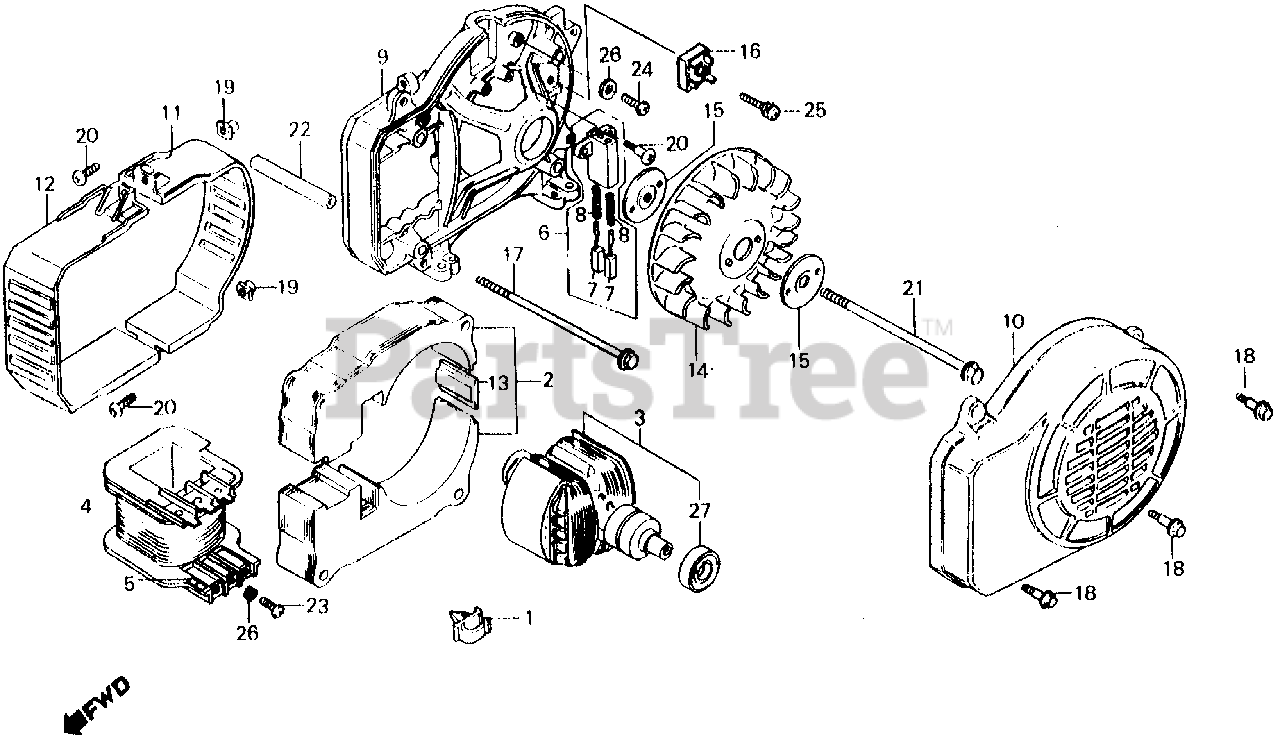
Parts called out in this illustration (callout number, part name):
1	CLAMP, D.C. CABLE
2	CORE SET, STATOR
3	ROTOR (NOT AVAILABLE)
4	BOBBIN, STATOR COIL (NOT AVAILABLE)
5	MARK, WIRE COLOR
6	HOLDER ASSY., BRUSH
8	SPRING, BRUSH
9	HOUSING, RR. (NOT AVAILABLE)
10	COVER, GENERATOR END
11	COVER, R. STATOR
12	COVER, L. STATOR
13	STIFFENER, STATOR
14	FAN, COOLING
15	PLATE, FAN
16	DIODE, D.C.
17	BOLT, FLANGE (6X144) (NOT AVAILABLE)
18	BOLT, GENERATOR END COVER
19	NUT, SPECIAL (5MM)
20	BOLT, STATOR COVER SETTING
21	BOLT, FLANGE (8X180) (NOT AVAILABLE)
22	PIN, DOWEL (11X126)
23	SCREW, PAN (5X6)
24	SCREW, PAN (5X12)
25	SCREW-WASHER (4X18)
26	WASHER, SPRING (5MM)
27	BEARING, RADIAL BALL (6203UU)
